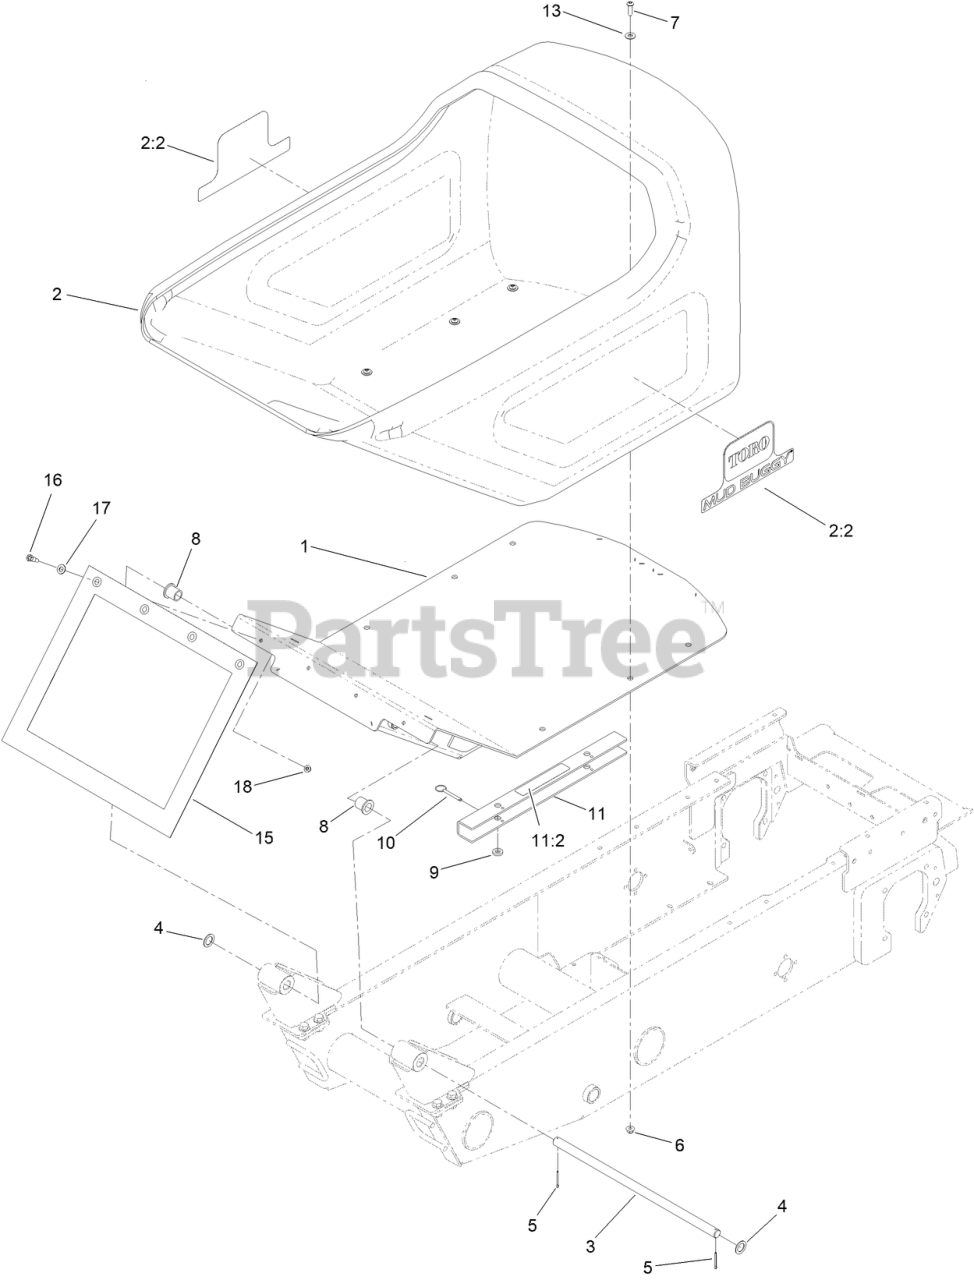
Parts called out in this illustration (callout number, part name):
1	FRAME-HOPPER ASM
2	HOPPER-MORTAR, ASM
2:2	DECAL-MUD BUGGY
3	SHAFT-PIVOT,TUB
4	SPACER
5	PIN-COTTER
6	NUT-HF, NI
7	SCREW-HSBH
8	BEARING-FLANGED
9	WASHER-NEOPRENE
10	PIN-COTTERLESS
11	ARM-LOCKING
11:2	DECAL-DANGER
13	WASHER-FLAT
15	SHIELD-SPLATTER
16	BOLT-SHOULDER
17	WASHER-FLAT
18	NUT-HF, NI
